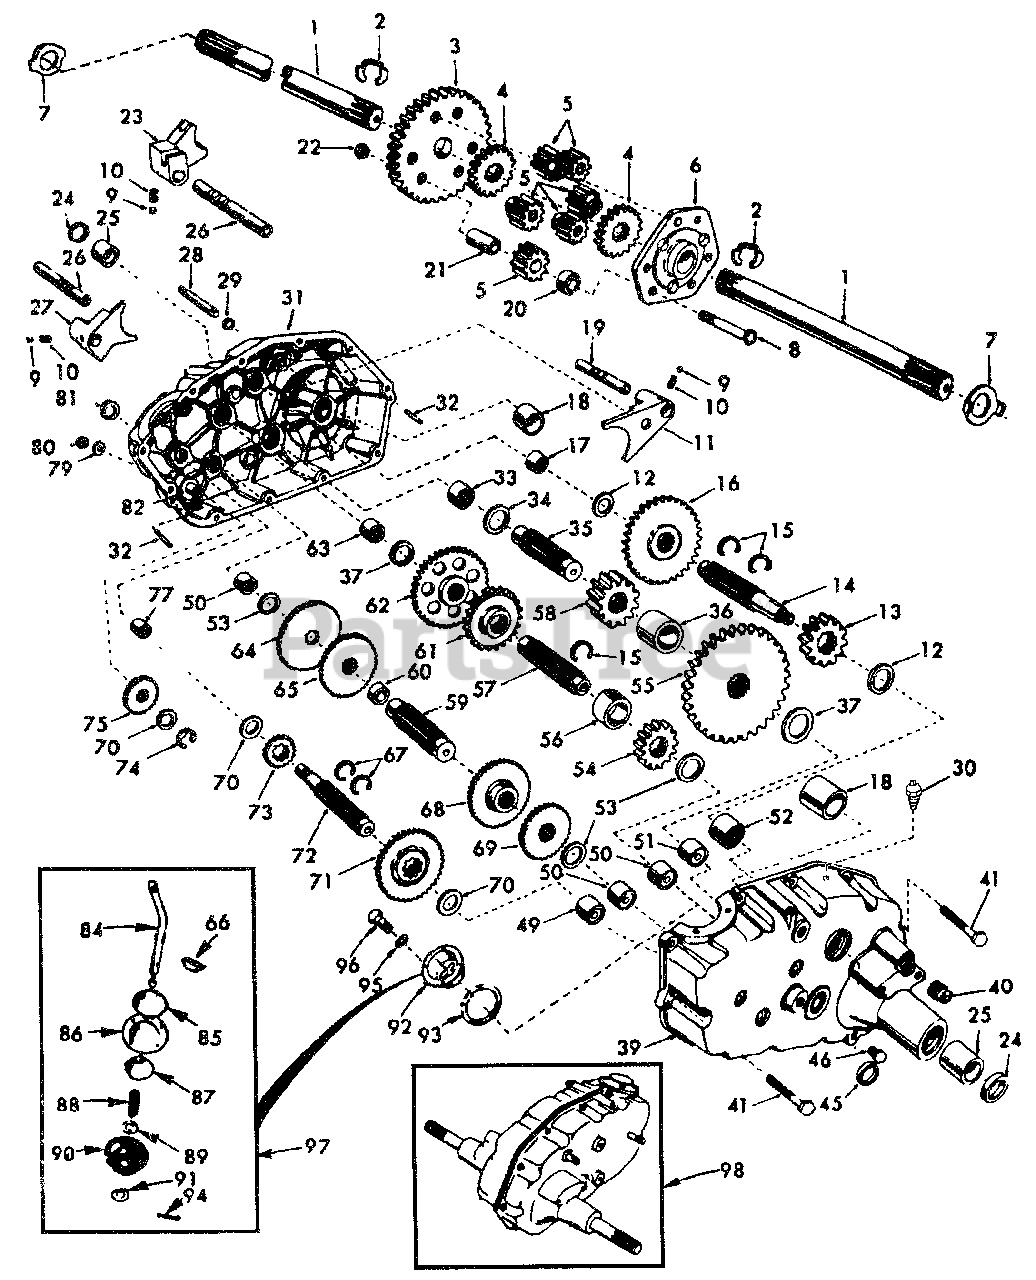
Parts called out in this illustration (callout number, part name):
1	Axle Shaft
2	Retaining Ring
3	Final Drive Gear
4	Differential Gear
5	Differential Pinion
6	Differential Carrier
7	Axle Thrust Washer
8	Bolt, Hex Head 3/8-24 x 3-1/4 (1" Thread Length)
9	Steel Ball
10	Spring Shift Fork Detent
11	Shift Fork, High-Low Range
12	Thrust Bearing Race
13	4th Reduction Pinion
14	3rd Reduction Gear Shaft
15	Snap Ring, Crescent Type
16	High-Low Range Gears
17	Needle Bearing
18	Sintered Iron Bearing.
19	Shift Fork Shaft, High-Low Range
20	Differential Pinion Spacer
21	Differential Pinion Bushing
22	Gripco Centerlock Nut 3/8-24
23	Shift Fork, R.H.
24	Oil Seal
25	Sintered Iron Bearing
26	Shift Fork Shaft
27	Shift Fork, L.H.
28	Shift Shaft, High-Low Range
30	Pressure Relief Valve
31	Gearcase, Reverse Idler Shaft and Bearings, R.H.
33	Needle Bearing
34	Thrust Bearing Race
35	4th Reduction Gear Shaft
36	4th Reduction Gear Spacer
37	Thrust Bearing Race
39	Gearcase and Bearings, L.H.
40	Pipe Plug 1/2-14 N.P.T.
41	Bolt, Hex 5/16-18 UNC x 1-1/4
46	Pipe Plug 1/4-18 N.P.T.
49	Needle Bearing
50	Needle Bearing
51	Needle Bearing
52	Needle Bearing
53	Thrust Bearing Race
54	3rd Reduction Pinion, Low
55	4th Reduction Gear
56	3rd Reduction Pinion Spacer
57	2nd Reduction Gear Shaft
58	Final Drive Pinion
59	1 st Reduction Gear Shaft
60	1 st Reduction Shaft Spacer
61	3rd Reduction Pinion High
62	2nd Reduction Gear
63	Needle Bearing
64	Low Speed Gear and 2nd Reduction Pinion Cluster
65	Reverse Gear
66	Key, Hi-Pro 1/8 x 17/32
67	Snap Ring, Crescent Type
68	Intermediate Speed Gear
69	High Speed Gear
70	Thrust Bearing Race
71	Intermediate and High Speed Cluster Pinions
72	Input Shaft
73	Low Speed Pinion
75	Reverse Idler Gear
77	Needle Bearing
79	Sealing Washer
80	Nut, Hex, Jam 7/16-20
81	Oil Seal
82	Reverse Idler Shaft
84	Gearshift Lever, Bent
85	Gearshift Cap
86	Gearshift Ball Cover and Pin
87	Shift Lever Guide Ball, Keyed
89	Washer 15/32 x 15/16 x 16 Gauge
90	Shift Mechanism Seal
91	Washer 9/16 x 15/16 x 12 Gauge
92	Gearshift Gate and Reinforcement
93	Shift Ball Cover Gasket
94	Cotter Pin 1/8 x 3/4
95	Washer, Lock 5/16
96	Bolt, Hex Head 5/16-18 UNC x 7/8
97	Gear Shift Lever Assembly
98	Transaxle, 6 Speed
